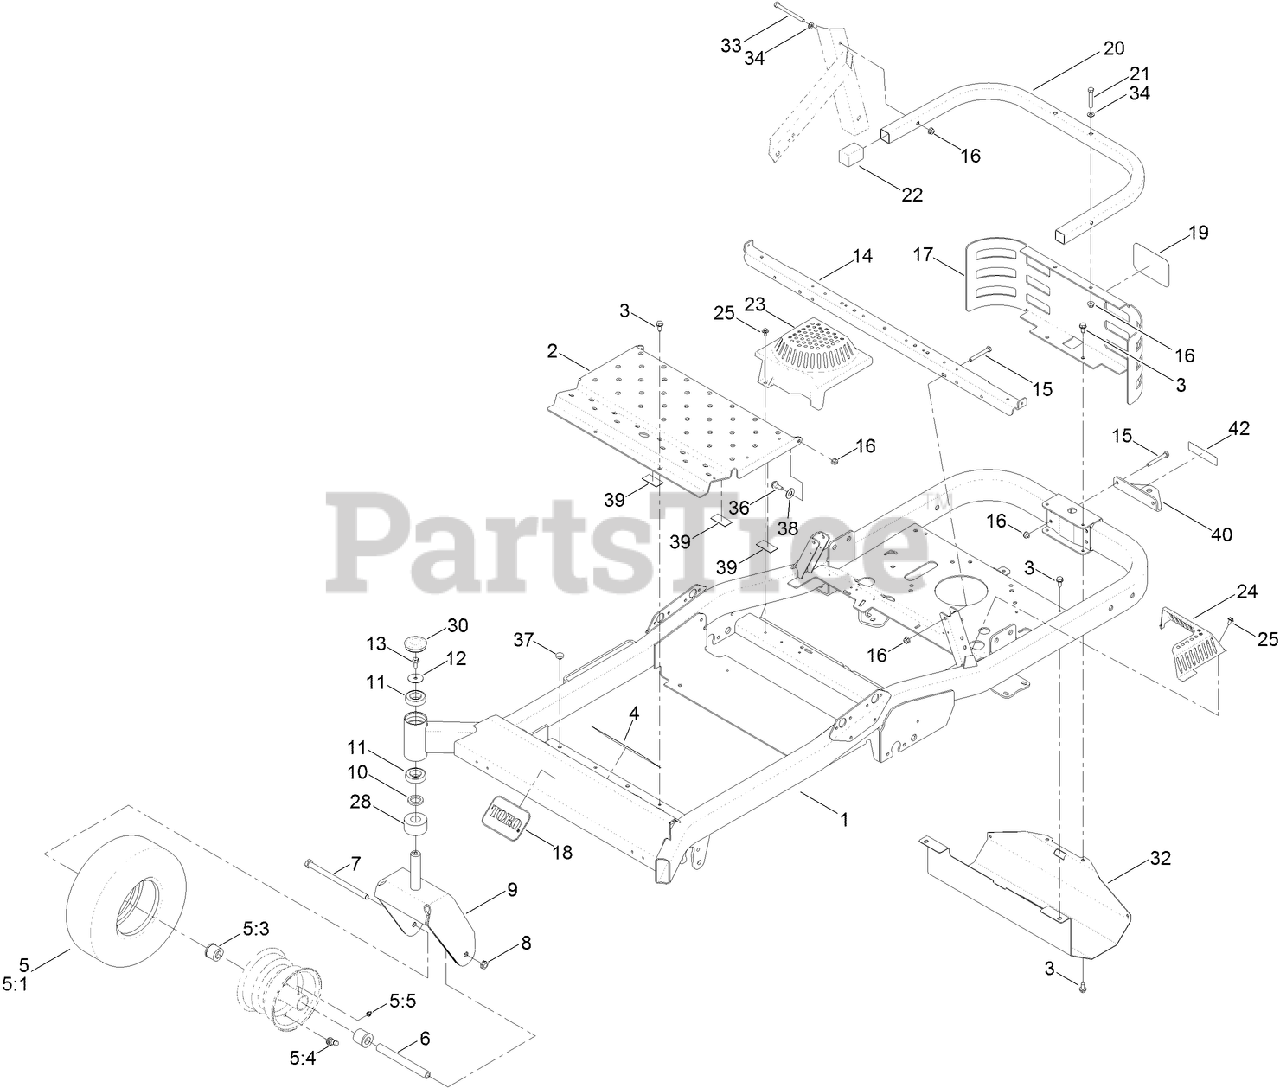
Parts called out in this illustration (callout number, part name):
1	FRAME ASM
2	PAN-FLOOR
3	SCREW-HWHTF
4	DECAL-DANGER
5	TIRE AND WHEEL ASM
5:1	TIRE-13 INCH SMOOTH
5:3	BUSHING-FLANGE
5:5	FITTING-GREASE
6	SPANNER
7	SCREW-HH
8	NUT-HEX
9	FORK-CASTER
10	WASHER-THRUST
11	BEARING-BALL
12	WASHER-FLAT
13	SCREW-HHF
14	SUPPORT-SEAT
15	SCREW-HH
16	NUT-HF, NI
17	GUARD-REAR
18	DECAL
20	TUBE-GUARD
21	SCREW-HH
23	COVER-FAN, RH
24	COVER-FAN, LH
25	SCREW-HHFTF
28	SPACER-CASTER
30	CAP-GREASE
32	SHIELD-HEAT
33	SCREW-HH
34	WASHER-PLAIN
36	SCREW-SHOULDER
37	BUMPER
38	WASHER-TEFLON
39	PAD-RUBBER
40	BRACKET-HITCH
